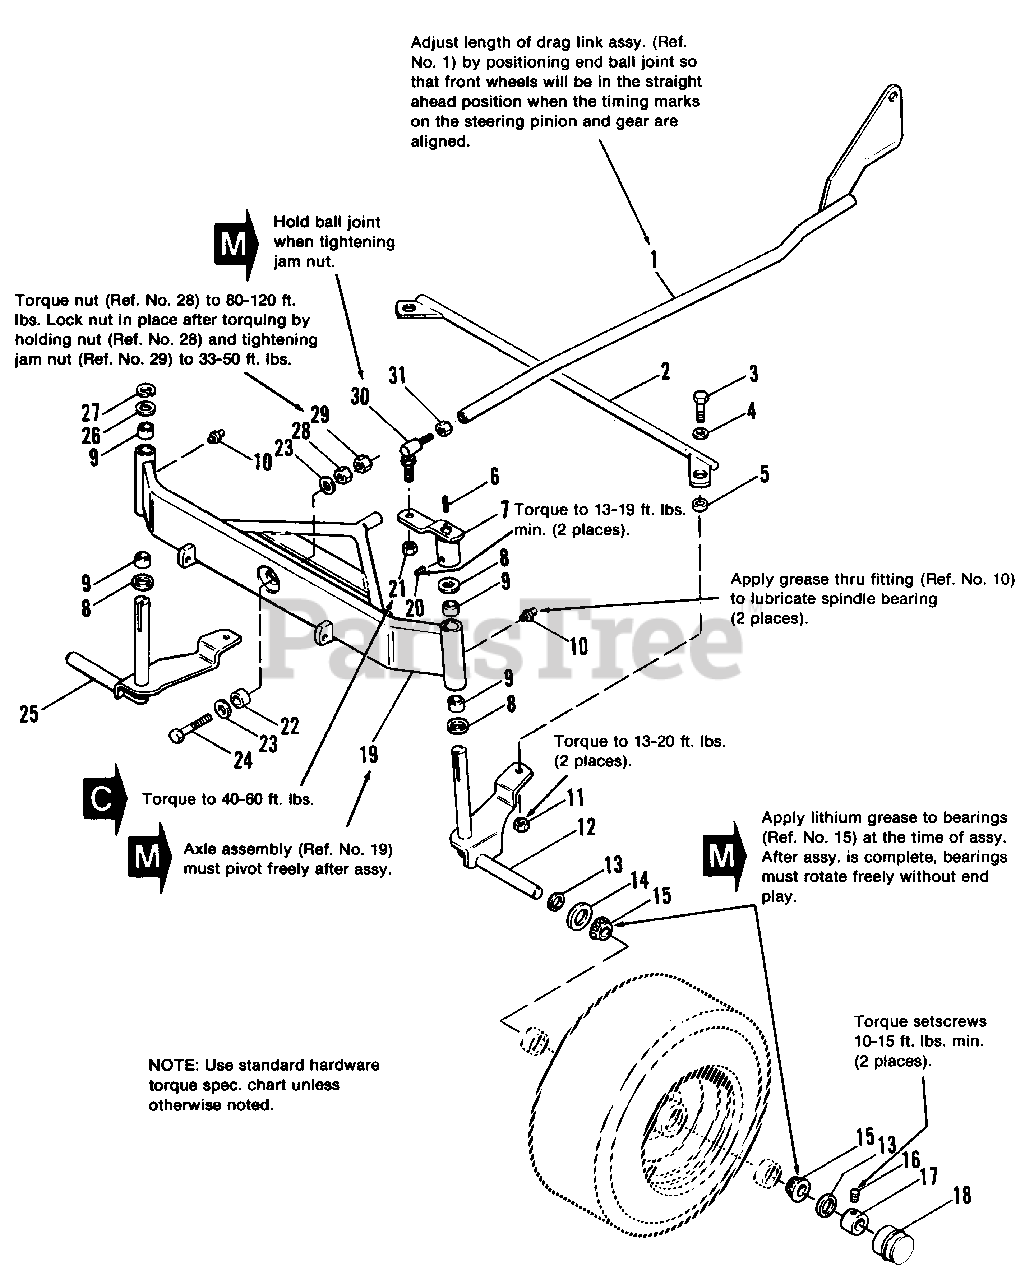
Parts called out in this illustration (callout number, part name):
1	LINK ASSY., Drag
2	ROD ASSY., Tie
3	CAPSCREW, Hex Hd., 3/8-16 x 1
4	WASHER, Plain, 3/8
6	KEY, Square
7	ARM ASSY., Steering
8	WASHER
10	FlTTING, Grease
11	LOCKNUT, Hex, 3/8-16
12	SPINDLE ASSY., L.H.
15	CONE, Bearing
16	SETSCREW, 5/16-18 x 5/16
17	COLLAR, Set
18	CAP, Hub
19	AXLE ASSY., Front (Incl. Ref. No. 9)
20	SETSCREW, 5/16-18 x 1/2
21	LOCKNUT, Hex, 1/2-20
23	WASHER, Plain, 1/2
24	CAPSCREW, Hex Hd., 1/2-13 x 2-1/4
25	SPINDLE, ASSY., R.H.
27	RING, Retaining
28	LOCKNUT, Hex, 1/2-13
29	LOCKNUT, Hex, Jam, 1/2-13
31	LOCKNUT, Hex, Jam, 1/2-20
